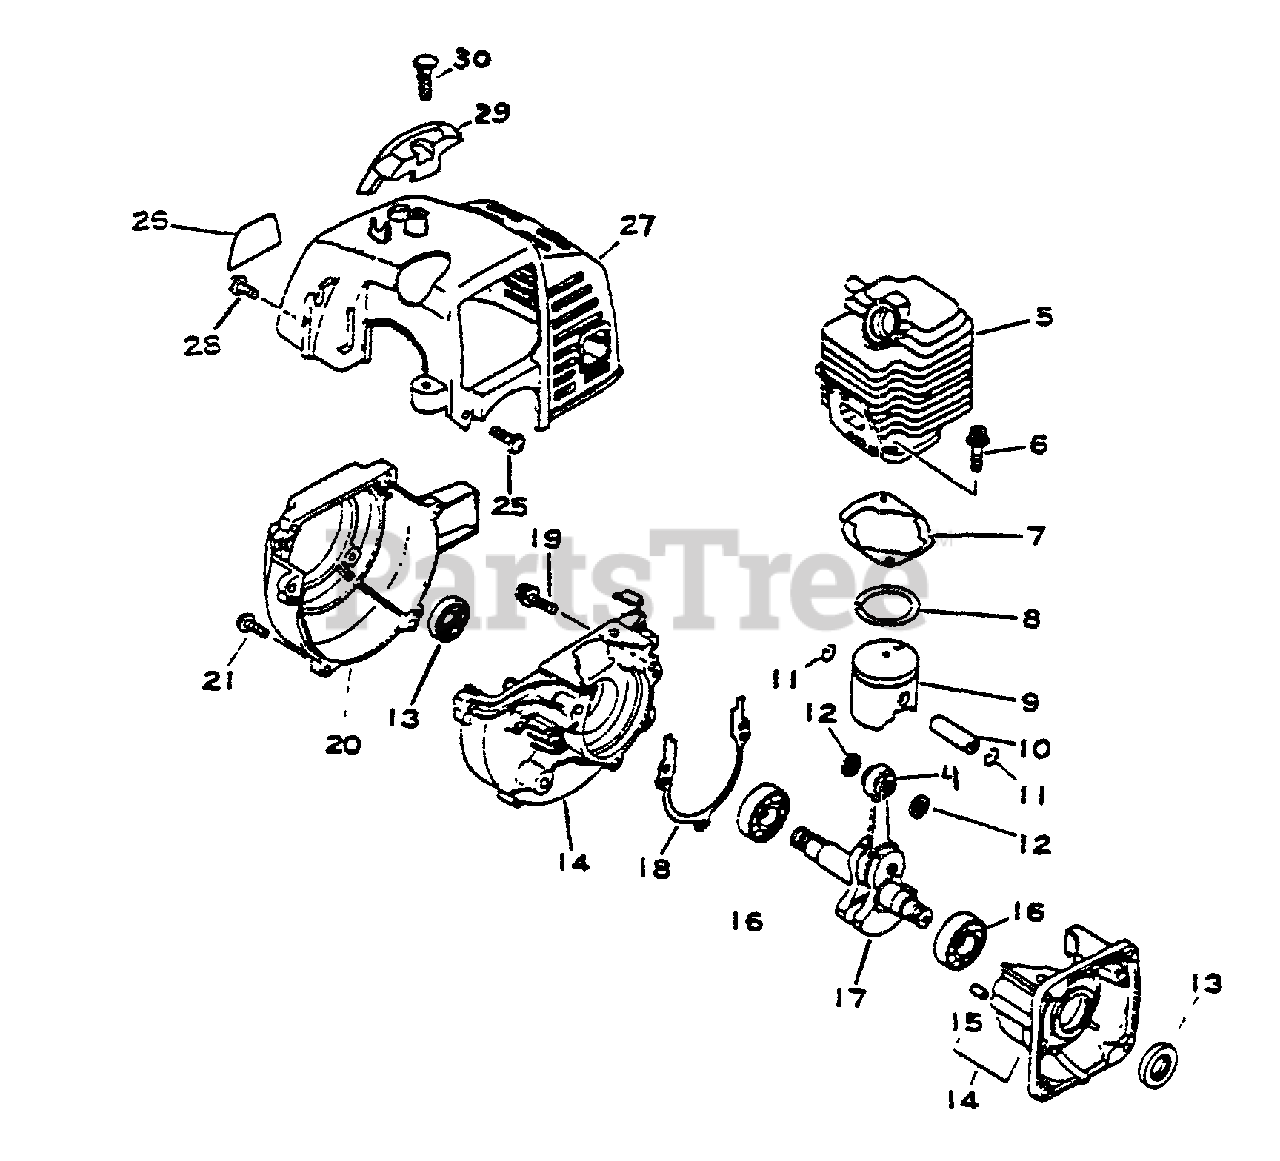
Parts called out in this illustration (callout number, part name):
4	Bearing, Needle
5	Cylinder
6	Bolt, H. S. 5=22
7	Gasket, Cyl, Base
8	Ring, Piston
9	Piston
10	Pin, Piston
11	Circlip, Piston Pin
12	Spacer, Piston Pin
13	Oilseal
14	Crankcase Set
15	Pin, Dowel
16	Bearing, Ball 6201
17	Crankshaft Assembly
18	Gasket, Crankcase
19	Screw 5=28
20	Cover, Fan
21	Screw 4=16
25	Screw 4=16
26	Label, Model
27	Cover, Cylinder
28	Screw 4=12
29	Guard, Top
30	Screw 5 * 16
